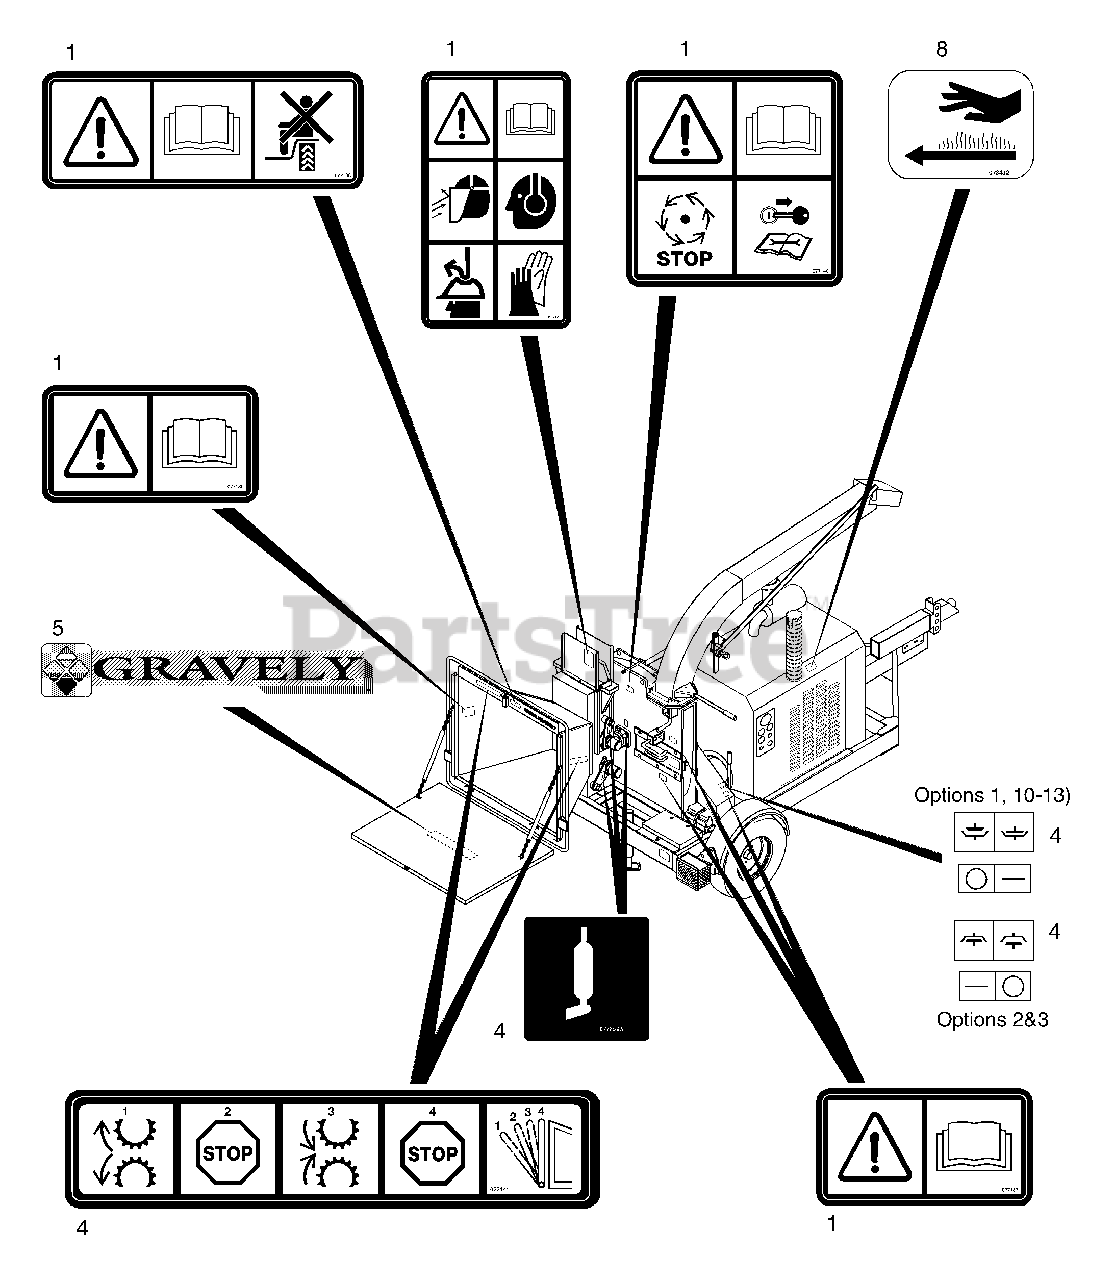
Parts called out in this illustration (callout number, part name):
1	Decal Set-Chipper CE
4	Decal Set-Chipper Black/White
5	Decal-Gravely Name/Logo Set
8	Decal-Hot Surface
